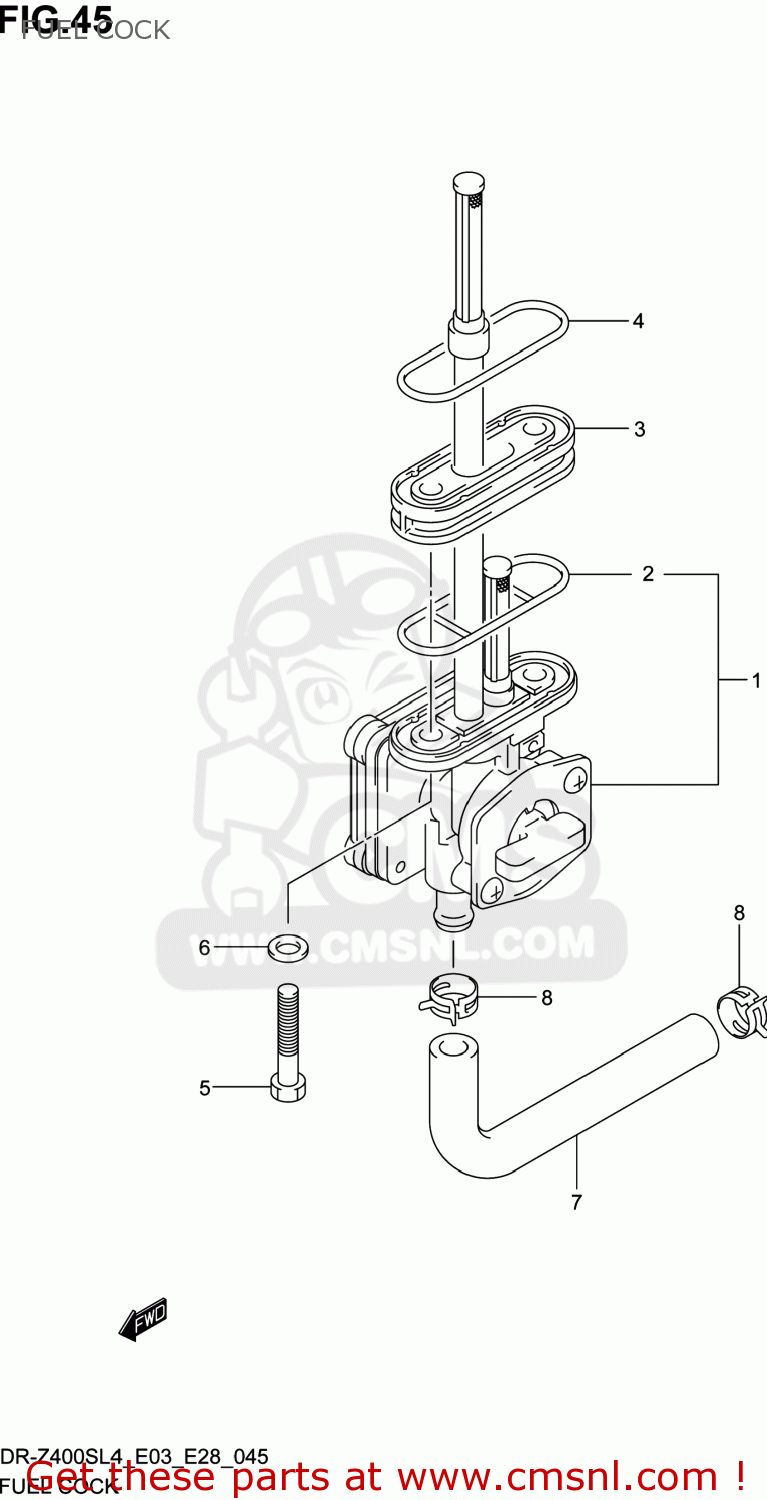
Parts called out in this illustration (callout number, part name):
1	COCK ASSY,FUEL
2	GASKET,JOINT (NAS)
3	SPACER,FUEL COCK
4	GASKET,FUEL COCK (NAS)
5	SCREW(6X30)
6	GASKET(6.4X11.5X0.8) (NAS)
7	HOSE,FUEL
8	CLIP
